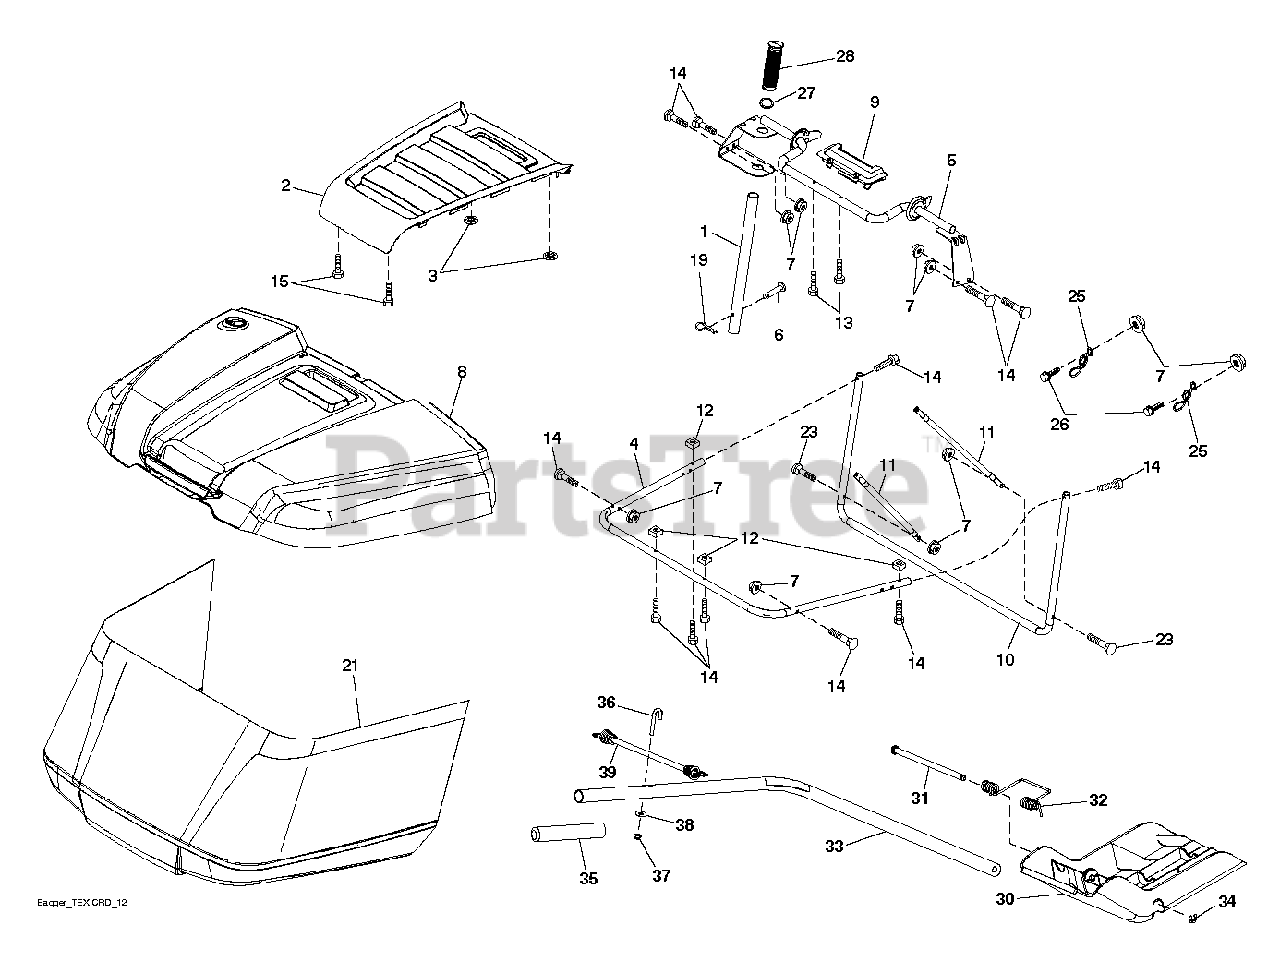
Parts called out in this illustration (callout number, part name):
1	TUBE.HANDLE.BAGGER.CRD/SRD.BLA
2	APPLIQUE.TOP.BAG.SRD.ORANGE
3	NUT.PUSH.156
4	SUBASM.TOP.TUBE.TEX.CRD
5	FRAME.ASM.TOP.BAGGER.SRD
6	RIVET,DRILLED
7	NUT T
8	BAGGER.TOP.SRD.APPLIQUE
9	INSERT.HANDLE.BAGGER.(2 2)
10	FRAME FRAME.FRONT.TEX.CRD
11	BRACE BRACE SIDE TUBE
12	NUT.SQUARE.1/4
13	SCREW.1/4X1.150.HXWSH
14	BOLT.SHOULDER.HX.WSH.1/4X1.150
15	SCREW,#8.FLAT.HEAD.DRILL.TIP
19	PIN.COTTER.5/16.BOW TI
21	BAG SUBASM. TEX CRD GEN 2 HUSQ
25	SPRING.LATCH.BAGGER.SRD
26	SCREW HEX CRT
27	RB GROMMET.RUBBER.SRD
28	GRIP.HANDLE.BLACK
30	PLUG PLUG
31	PIN PIN.HINGE
32	SPRING SPRING DOUBLE TORSION
33	SHAFT SHAFT TEX CRD MULCH PLU
34	E-RING.5/16"
35	GRIP GRIP MULCH PLUG HAND
36	BOLT BOLT J
39	BUBGEE BUBGEE TEX CRD
